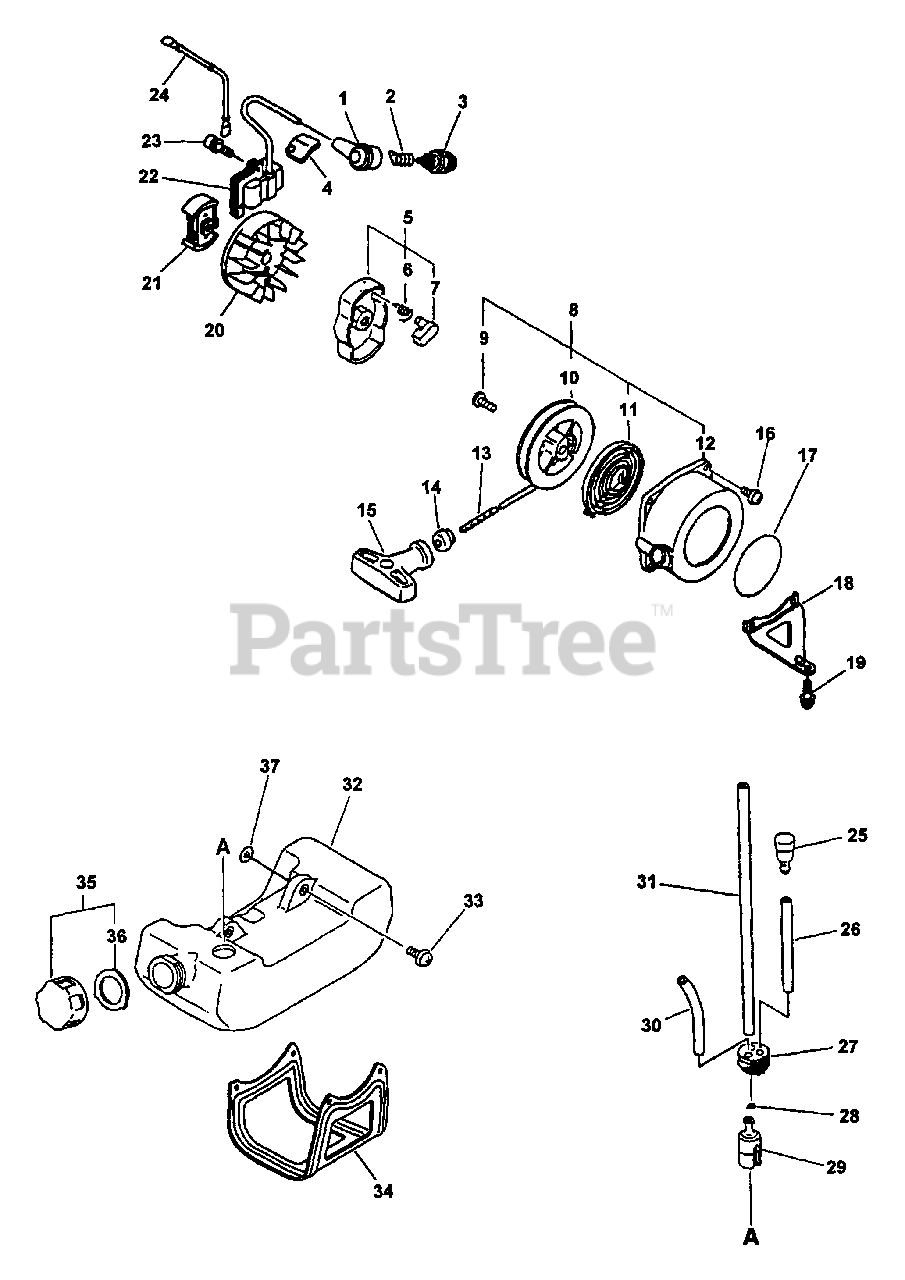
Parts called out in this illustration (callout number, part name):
1	CAP, SPARK PLUG
2	TERMINAL, SPARK PLUG CAP
3	SPARK PLUG -- BPM-7Y
4	COVER, DUST
5	STARTER PAWL ASSY
6	SPRING, RETURN
7	PAWL, STARTER - BLACK
8	STARTER ASSY
10	REEL, ROPE
11	SPRING, REWIND
12	CASE, STARTER
13	ROPE, STARTER
14	GUIDE, ROPE
15	GRIP, STARTER
16	SCREW - 4X16
17	LABEL - ECHO
18	SUPPORT, REAR HANDLE
19	SCREW - 5X16
20	FLYWHEEL
21	CLUTCH ASSY
22	COIL, IGNITION
23	SCREW - 4X22
24	LEAD - IGNITION
25	VENT, FUEL TANK
26	PIPE - 3X5X30 -- BLACK
27	GROMMET
28	CLIP - 6
29	FILTER, FUEL
30	PIPE - 3X6X80 -- CLEAR
31	PIPE - 3X5X160 -- BLACK
32	TANK, FUEL
33	SCREW - 5X16
34	GUARD, FUEL TANK
35	CAP ASSY
36	GASKET, CAP
37	WASHER - 5
